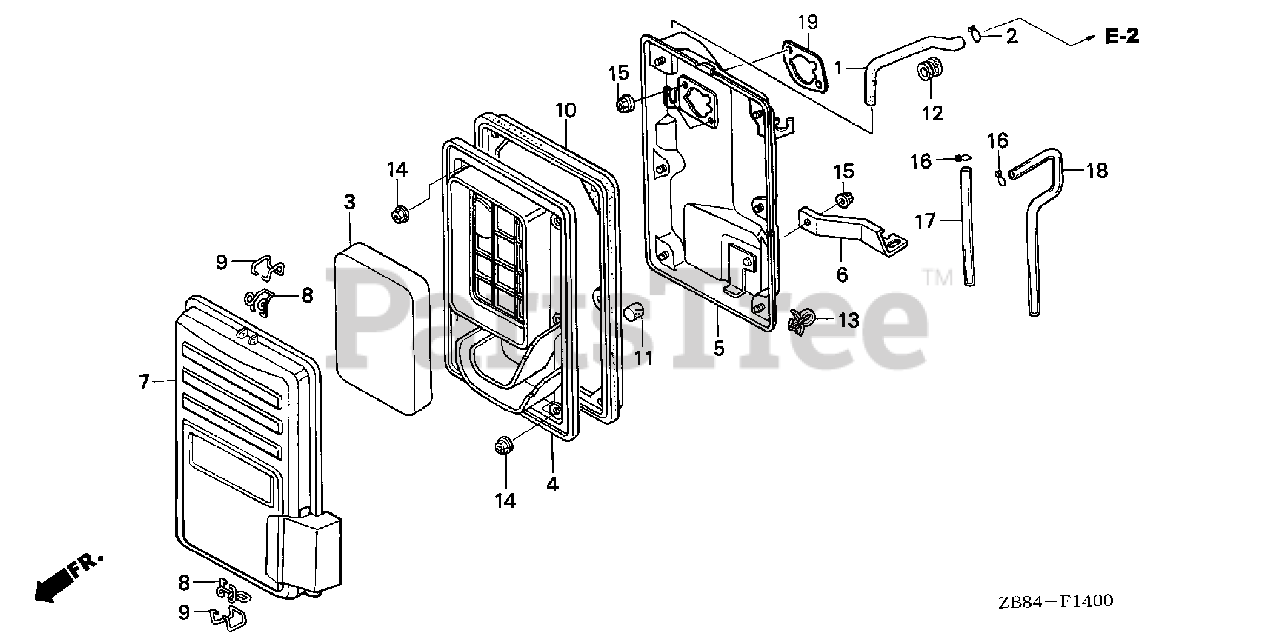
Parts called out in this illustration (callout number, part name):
1	TUBE, BREATHER
2	CLIP, BREATHER TUBE
3	ELEMENT, AIR CLEANER
4	SEPARATOR, AIR CLEANER
5	HOUSING, AIR CLEANER
6	STAY, AIR CLEANER
7	COVER, AIR CLEANER
8	CLIP A, AIR CLEANER WIRE
9	CLIP B, AIR CLEANER WIRE
10	SEAL, AIR CLEANER
11	FILTER, DRAIN TUBE
12	GROMMET, FENDER
13	CLIP, WIRE HARNESS
14	NUT, FLANGE (5MM)
15	NUT, FLANGE (6MM)
16	CLIP, TUBE (C8)
17	BULK HOSE, VINYL (4.5X8X1000) (4.5X8X230)
18	BULK HOSE, VINYL (4.5X8X1000) (4.5X8X380)
